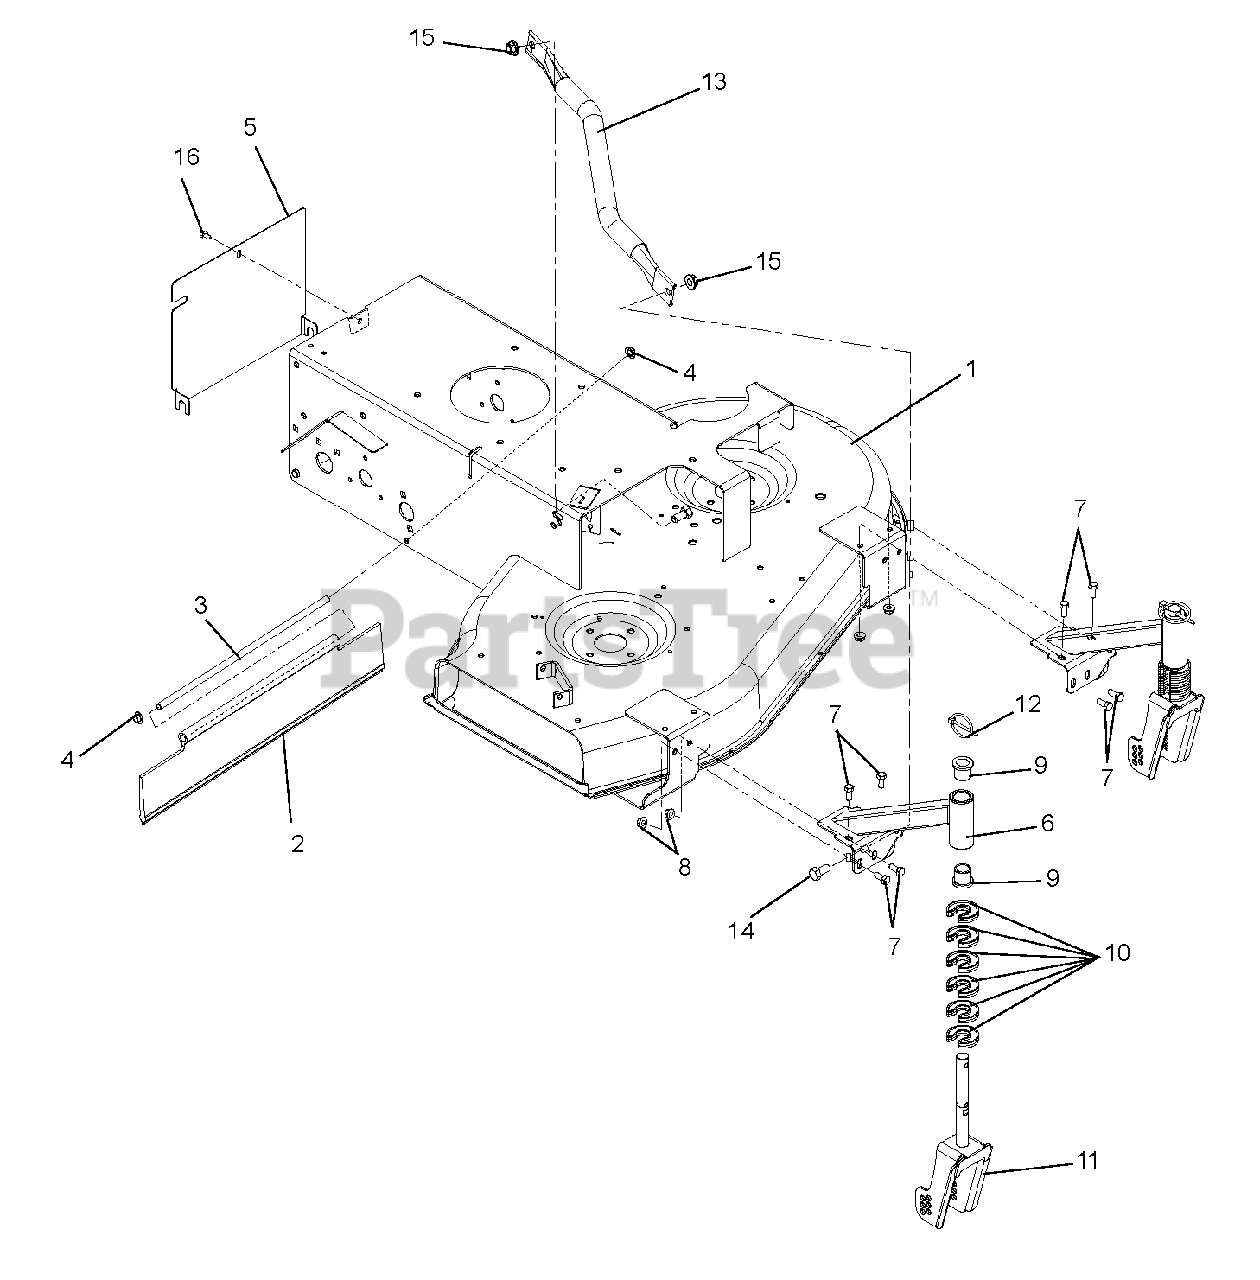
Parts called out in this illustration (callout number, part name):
1	Chassis, Wide Area Walk
2	Guard, Rear Swivel
3	Rod, Trailing Shield
4	Nut, Push .312 Dia. PAL
5	Cover, Rear Chassis
6	Weldment, Caster Arm
7	Bolt, Hex .31-18 x .75
8	Nut, Locking Top Flange .31-18
9	Bushing, Flange .75 x .75 x 1.0
10	Clip, HOC Fixed
11	Fork, WAW Caster
12	Pin, Lynch .25 x 1.25
13	Strap, Frame Reinforcing
14	Bolt, Hex .38-16 x .75
15	Nut, Locking Top Flange .38-16
16	Screw, Tapping .25-20 x .50
